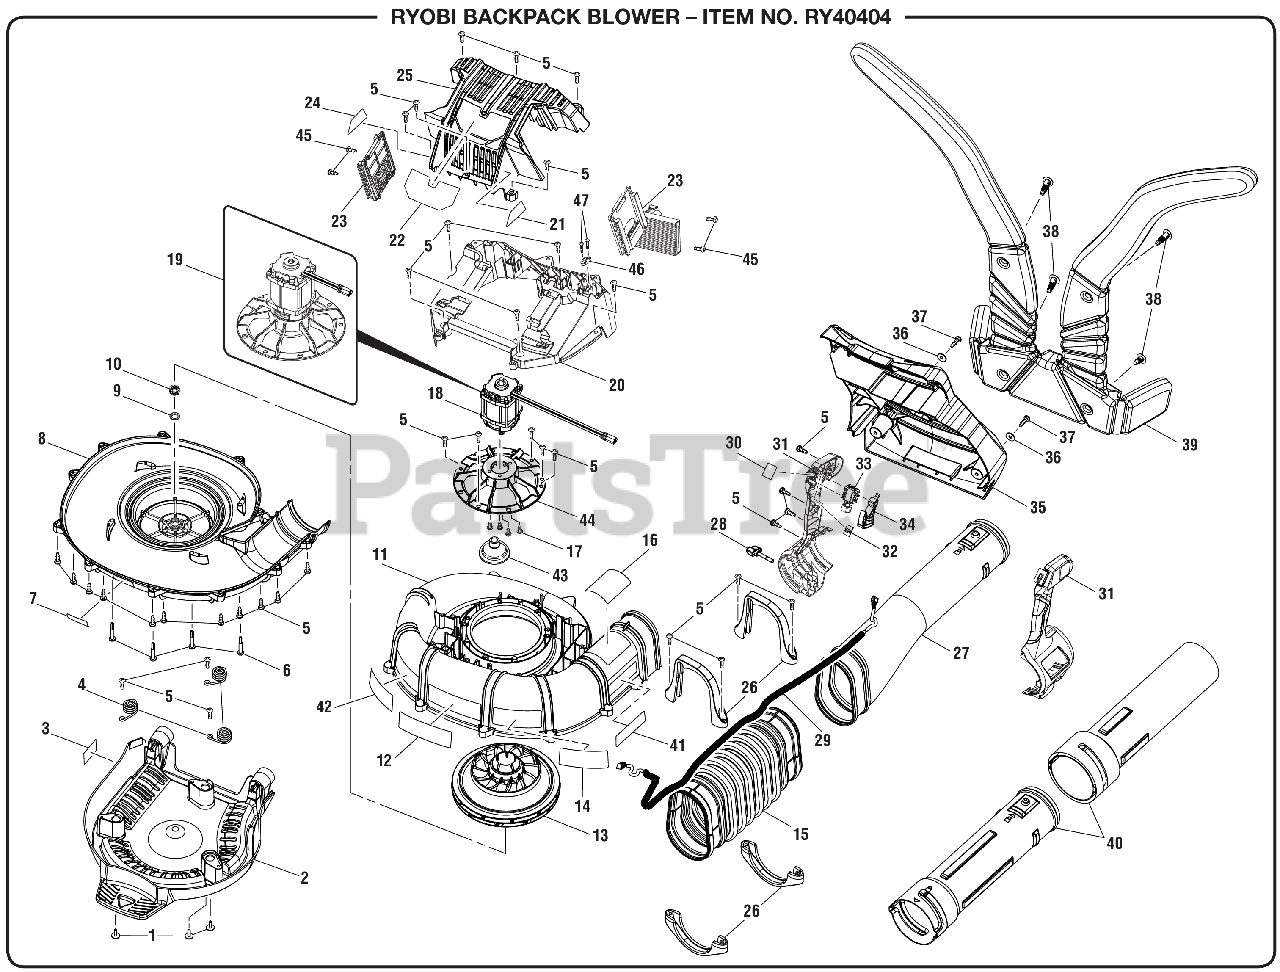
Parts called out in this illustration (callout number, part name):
1	Screw (10-14 x 16 mm)
2	Lower Frame Assembly
3	Data Label
5	Screw (10-14 x 19 mm, T25 Torx Truss Pan Hd. T.F.)
6	Shoulder Screw (M5 x 40 mm, T25 Torx Truss Hd. T.F.)
7	Hair Ingestion Warning Label
8	Outer Volute Assembly
9	Washer (OD18 x ID12.15 x 1.5t)
10	Wavy Spring (ID6.51 x HGT9.52)
11	Inner Volute Assembly
12	Ryobi Logo Label
13	Fan Assembly
14	MPH Label
15	Bellows Tube
16	Warning Icon Label
17	Screw w/Lock Washer (M5 x 8 mm, Pan Hd.)
18	Motor (40 volt)
19	Motor & Mount Assembly
20	Housing Cover (Bottom)
21	Warning Label (French)
22	40V Lithium Label
23	Motor Controller & Battery
24	Warning Label (Spanish)
25	Housing Cover Assembly
26	Clamp Assembly
27	Handle Blower Tube
28	Adjustment Knob (1/4-20 UNC)
29	Wire Assembly
30	Turbo Label
31	Throttle Handle & Cruise Control Assembly
32	Turbo Switch
33	Switch Assembly
35	Upper Frame
36	Washer (OD16 x ID6.8 x 1.5t)
37	SCREW (10-14 X 1 in.)
38	Harness Snap Fastener
40	Blower Tube Assembly
41	Battery Warning Label
42	CFM Label
43	Drive Coupler
44	Motor Mount
45	Screw, M4-18 x 12mm, T20 Torx Pan Head
46	Strain Relief Plate
47	Screw (M4 x 14 mm, T15 Torx Pan Hd.))
